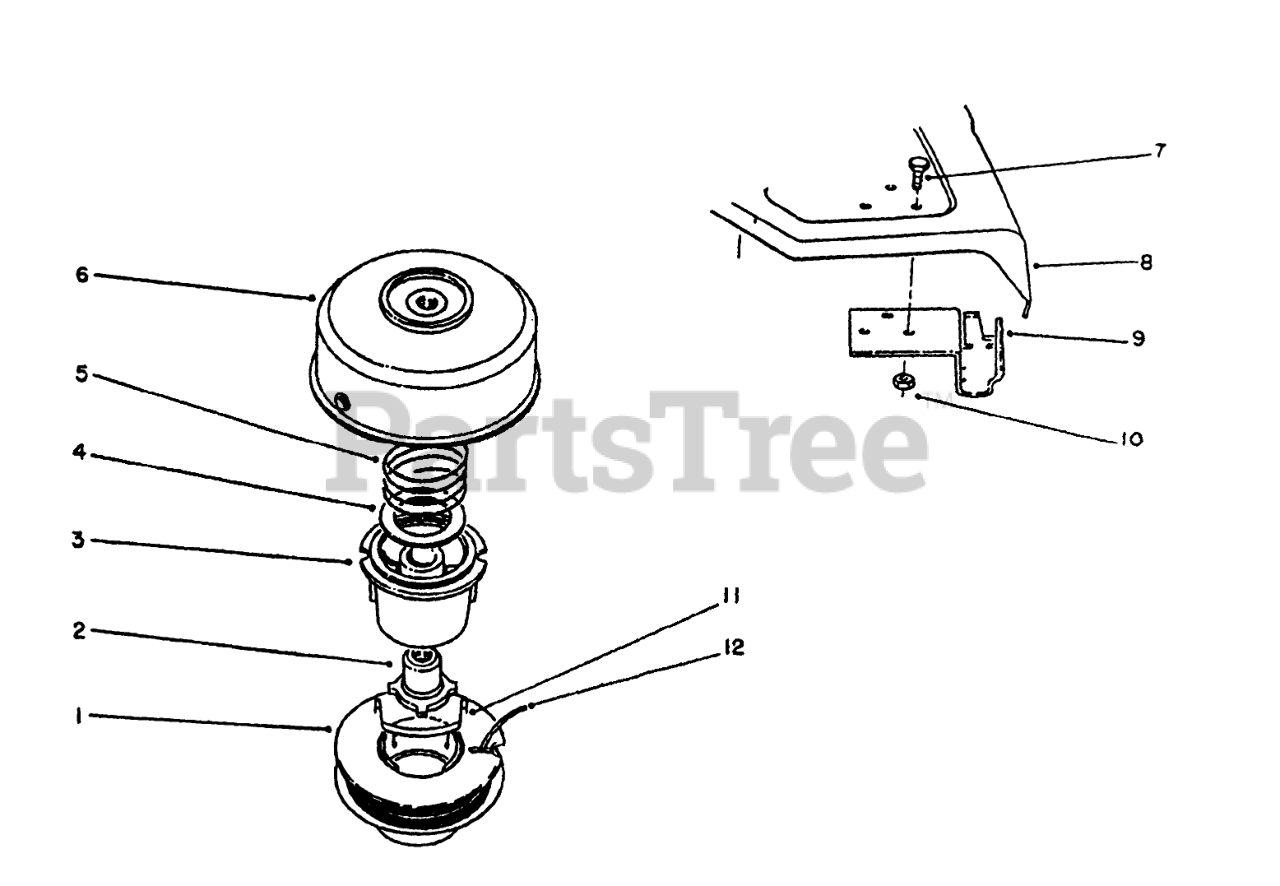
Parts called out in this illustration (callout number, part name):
1	SINGLE LINE(.095) SPL P
2	LH DRIVER
3	SPOOL CORE
4	WASHER-FLAT
5	SPRING
6	DRUM EYELET ASM
7	SCREW-SHH
8	Shield-Grass
9	BRACKET & KNIFE ASM
10	NUT-LOCK, NI
11	SADDLE-SPOOL CAP
